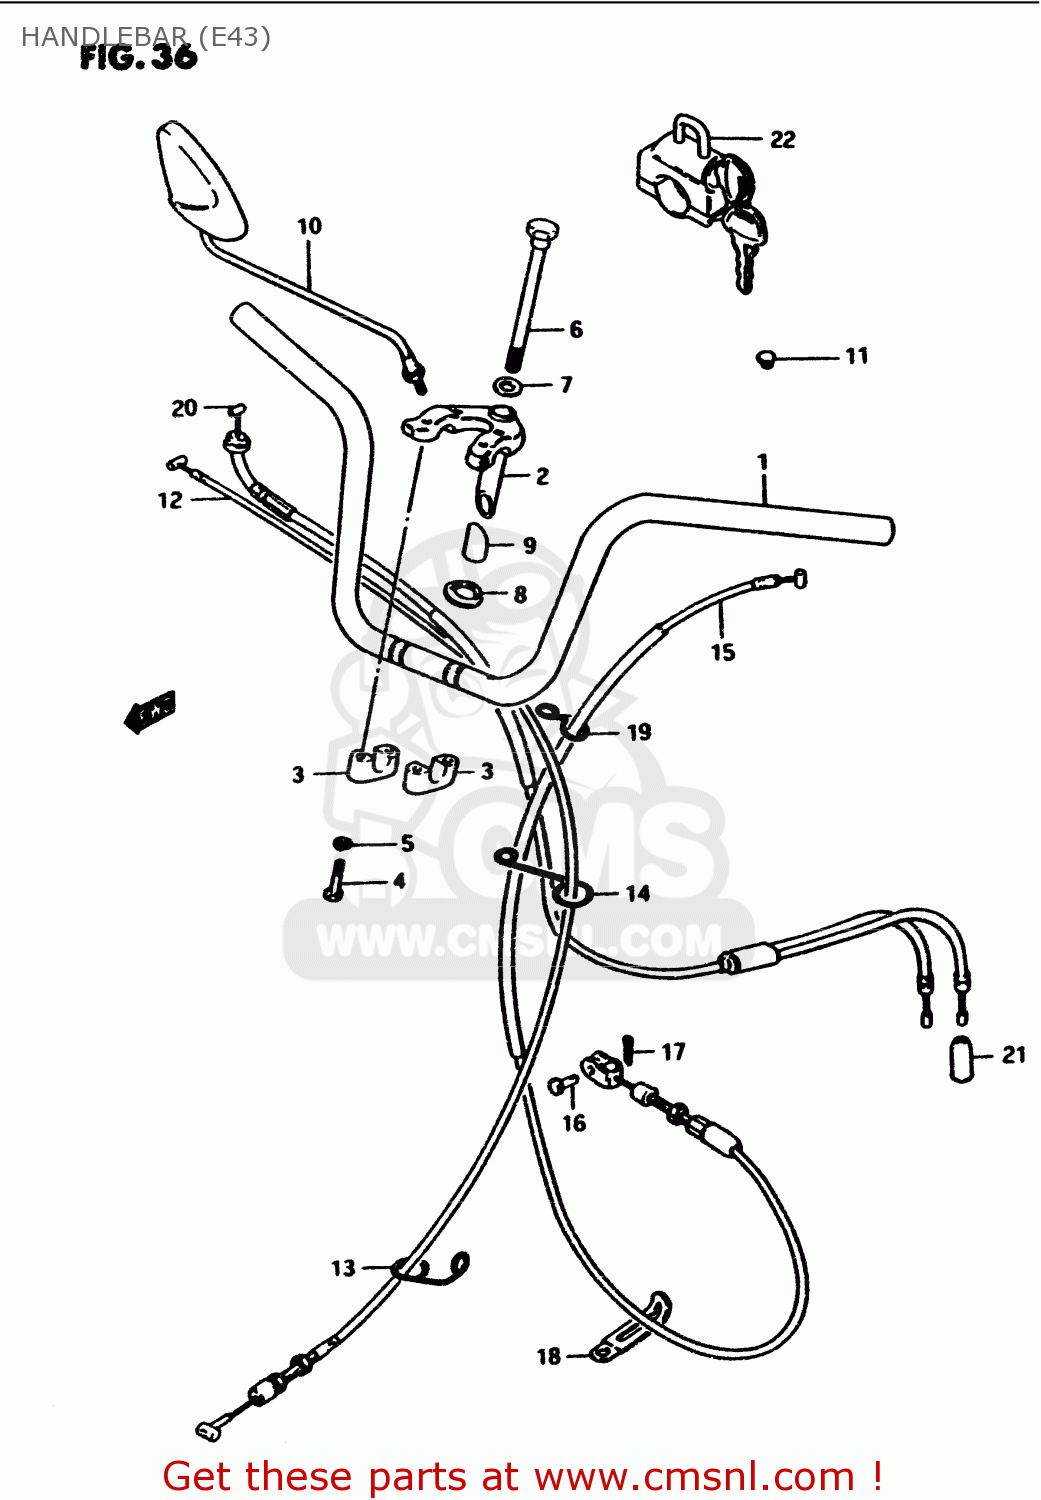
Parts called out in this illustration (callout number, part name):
1	HANDLEBAR
2	BRACKET,HANDLEBAR
3	HOLDER,HANDLE UPR
4	BOLT
5	WASHER,LOCK,8.
6	BOLT(12X114)
7	WASHER
8	STOPPER
9	STOP,HANDLE EXPANDER
10	MIRROR ASSEMBLY,RIGHT
11	CAP
12	CABLE,FR BRAKE
13	GUIDE
14	GUIDE,FR BRAKE CABLE UPR
15	CABLE ASSY,CLUTCH
16	PIN(L:13)
17	PIN
18	CLAMP L:35
19	GUIDE,CABLE
20	CABLE ASSY,THROTTLE
21	SEAL,DUST(7X18X30)
22	LOCK ASSY,HELMET
